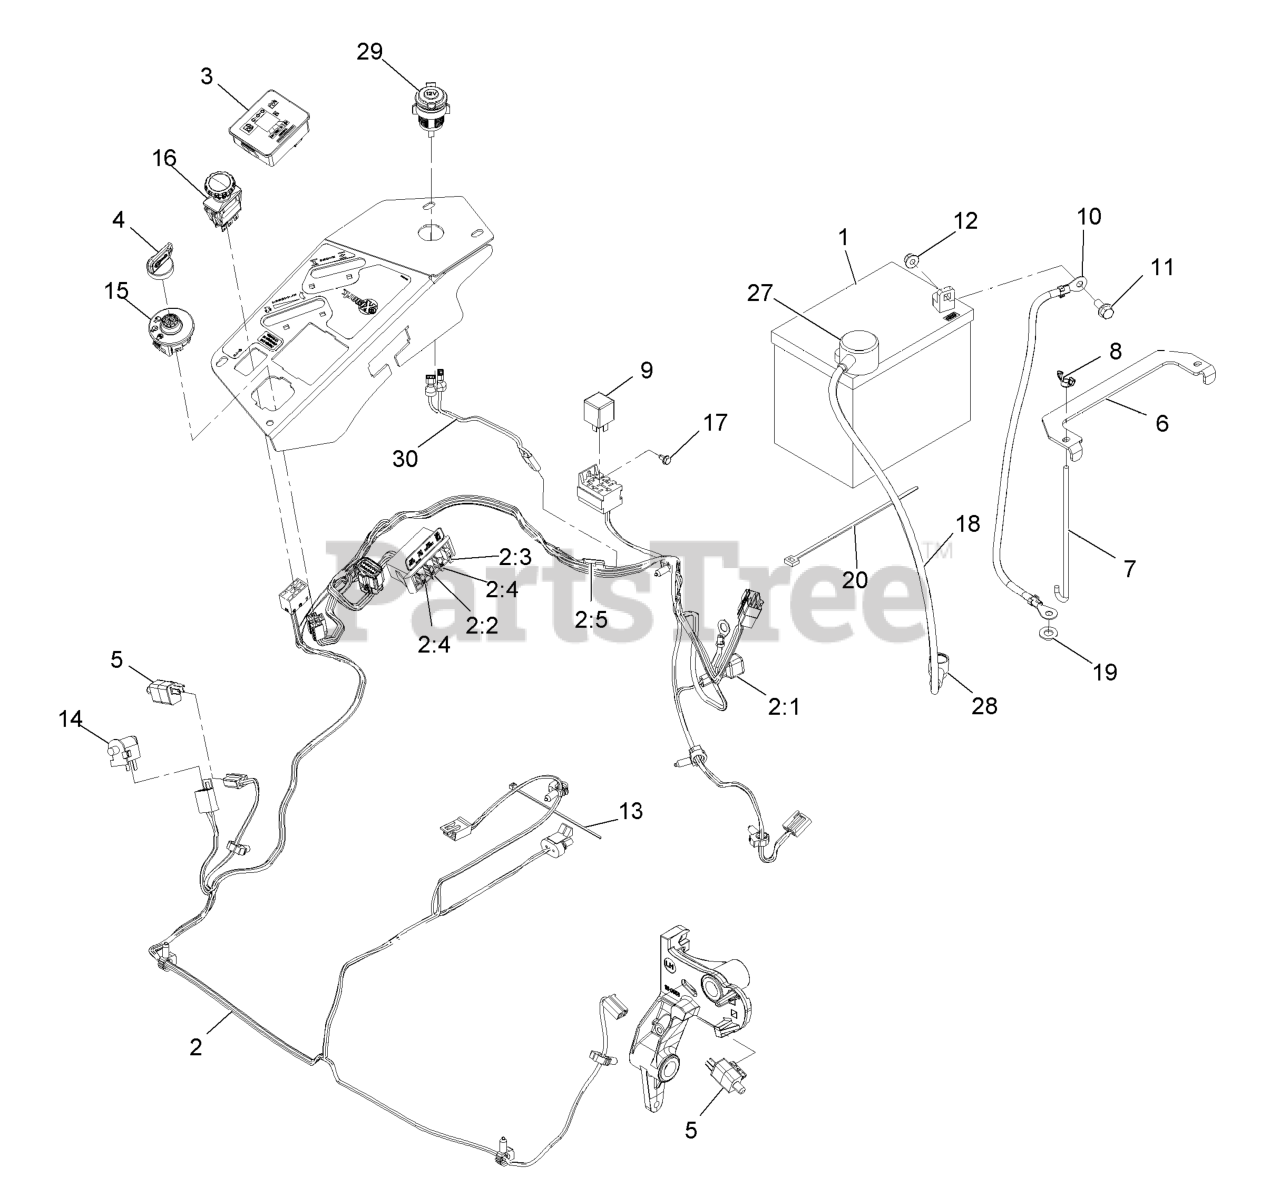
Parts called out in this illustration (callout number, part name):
1	Battery-Wet
2	HARNESS-WIRE, MAIN
2:2	FUSE-BLADE, 10 AMP
2:3	FUSE-BLADE, 15 AMP
2:4	FUSE-BLADE, 25 AMP
2:5	CAP-PLUG
3	FUEL/HOUR METER ASM
4	KEYS-IGNITION (SPARE PAIR
4	KEY-IGNITION
6	STRAP-TIE DOWN, BATTERY
7	BOLT-HOLDDOWN
8	WINGNUT
10	CABLE-BATTERY, NEGATIVE
11	SCREW-HHF
12	NUT-HF, NI
13	TIE-CABLE
14	SWITCH-BAIL
16	SWITCH-PTO, 10 AMP
17	SCREW-HWH
18	CABLE-BATTERY, POSITIVE
19	WASHER-FLAT
20	TIE-PLASTIC
27	INSULATOR-BATTERY
28	INSULATOR-SOLENOID
29	RECEPTACLE-12V
30	HARNESS, RECEPTACLE 12V
